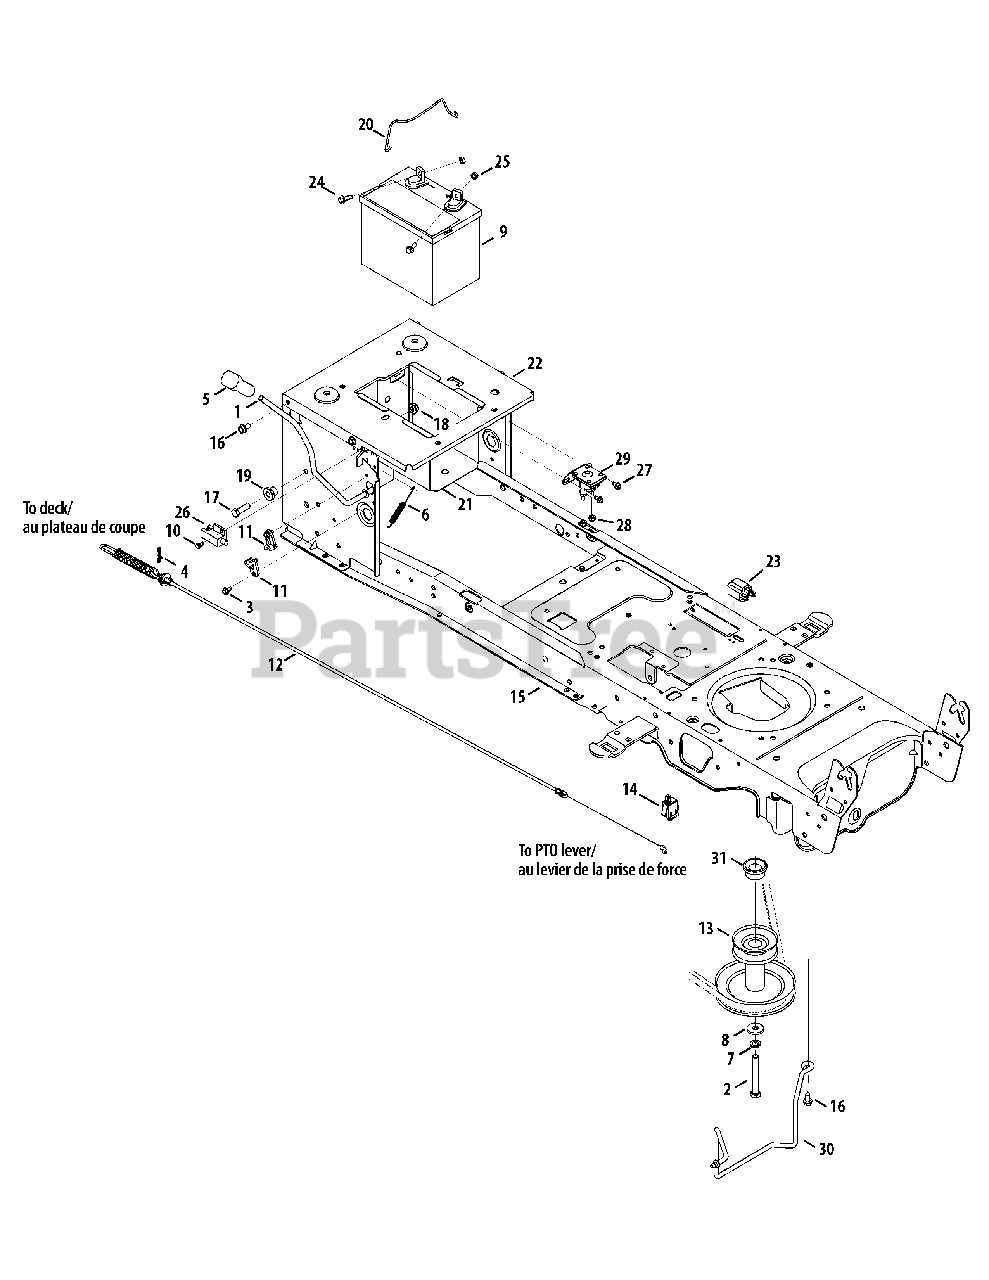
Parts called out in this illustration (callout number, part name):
1	Handle Ass’y , PTO
2	Hex Screw 7/16-20 x 3.5 Gr. 5
3	Hex Wash S-Tapp Screw 1/4-20 x .50
4	Bow-Tie Cotter Pin
5	Handle Grip 3/8
6	Extension Spring .38 Dia. x 5.6
7	Lockwasher 7/16 ID
8	Flat Washer .450 x 1.25 x .164
9	Battery 245 CCA (Dry)
10	Shoulder Screw #10-32 x .50
11	Bearing, PTO
12	Deck Engagement Cable
13	Engine Pulley 3.39 x 6.12 Dia.
14	Switch, Plunger, snap mount
16	Hex Wash Hd. Tapp Screw. 5/16-18 x .75
17	Hex Bolt 3/8-16 x 1.25
18	Flange Lock-Nut 3/8-16 Gr. F Nylon
19	Shoulder Spacer .38 x 1.0 x .70
20	Battery Retainer Rod
21	Battery Tray
22	Seat Frame Bracket
23	Switch, 3-Pole, (NC-NO-NO)-Brake
24	Hex Hd. Flg. Screw. 1/4-20 x .75 Gr. 5
25	Sems Hex Nut 1/4-20
26	Switch, Interlock
27	Hex Wash HD Tapp Screw 1/4-20 x .375
28	Hex L-Flanged Nut 1/4-20 Gr. F Nylon
29	Solenoid
30	Belt Keeper Rod
31	Spacer 1.010 x 1.4 x .825
